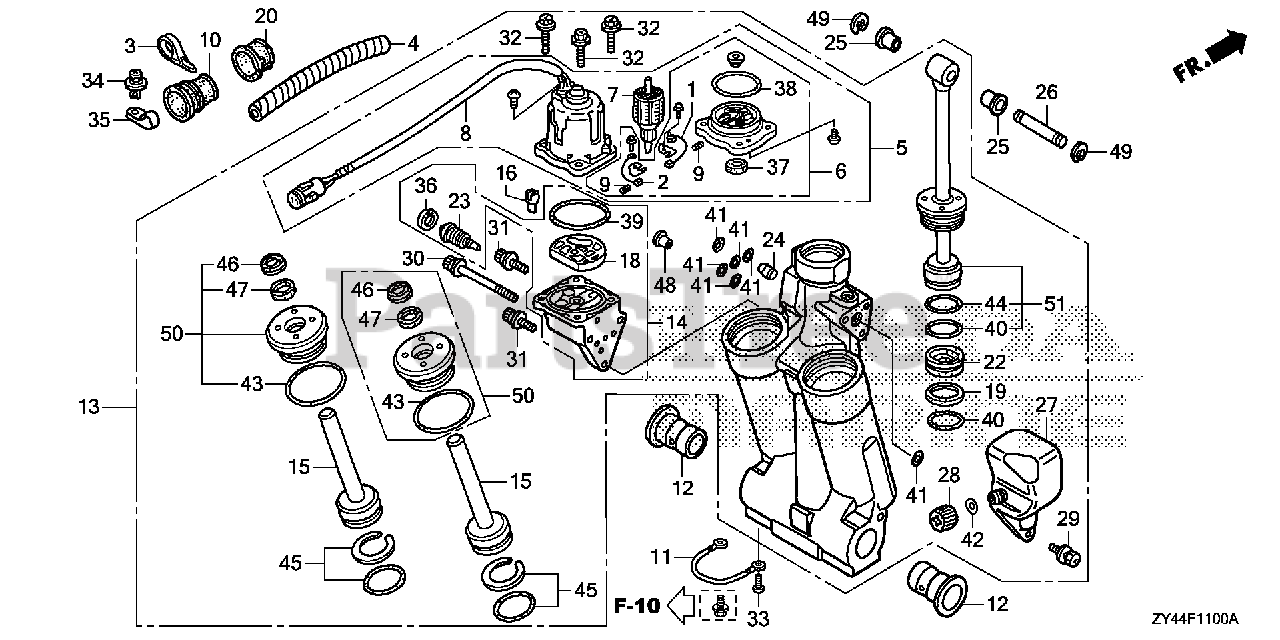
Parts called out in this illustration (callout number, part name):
1	BREAKER ASSY.
2	BRUSH ASSY.
3	BAND (BLACK 3.5X140)
4	TUBE, SPIRAL (12X14.6)
5	MOTOR ASSY., POWER TILT
6	BRACKET ASSY.
8	YOKE ASSY.
9	SPRING, MOTOR
10	GROMMET, CASE (LOWER) (C)
11	WIRE, LEAD (1.5X116MM)
12	BUSH, SWIVEL CASE
13	TRIM-TILT ASSY., POWER
14	PUMP ASSY.
15	ROD, PISTON (B)
16	JOINT, DRIVE
19	RING, BACK-UP
20	BUSH, MOTOR CODE
22	PISTON, FREE
23	VALVE, MANUAL
24	VALVE, RESERVOIR
25	BUSH, CYLINDER (LOWER)
26	PIN, CYLINDER (UPPER)
27	TANK, OIL
28	CAP, OIL TANK
29	BOLT, RECESSED
30	BOLT A, SOCKET
31	BOLT B, SOCKET
32	BOLT, HEX.
33	SCREW, PAN (6X8)
34	SCREW, RIVET (5X10)
35	CLIP (10.7MM)
36	CIRCLIP (INNER)
38	O-RING (2.0X70.5)
39	O-RING (1.8X69.6)
40	O-RING (3.5X38.7)
41	O-RING (1.8X7.7)
42	O-RING (1.9X11)
43	O-RING (3.5X35.7)
44	O-RING (3.5X41.7)
45	O-RING SET (3.5X31.7)
46	SEAL, WATER
48	COLLAR, ORIFICE
49	E-RING (15MM)
50	GUIDE, ROD
51	ROD, PISTON
